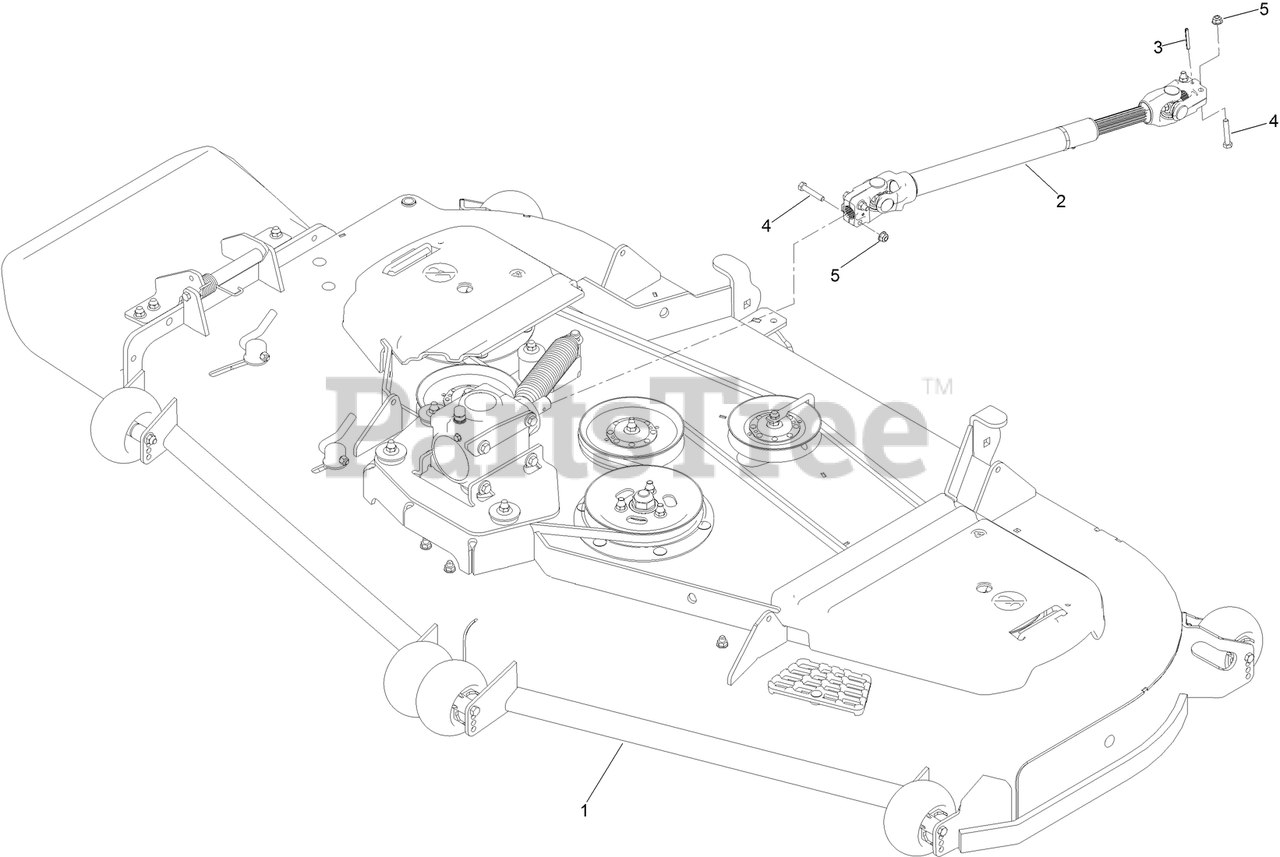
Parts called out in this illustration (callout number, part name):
1	DECK ASM
2	DRIVESHAFT ASM
3	PIN-ROLL
4	SCREW-HH
5	NUT-HF, NI
